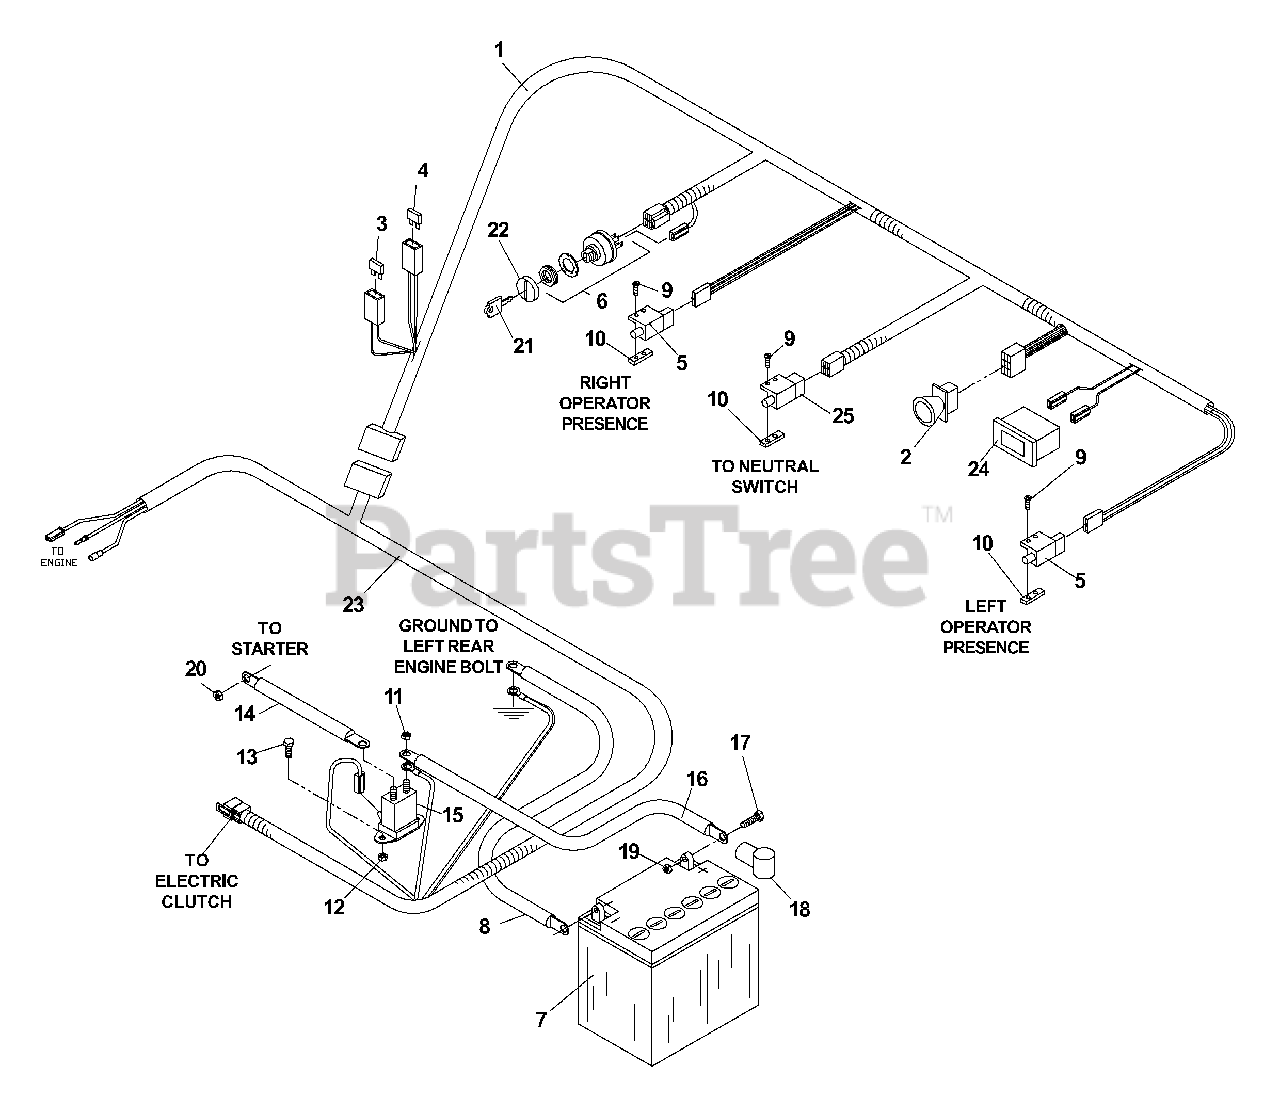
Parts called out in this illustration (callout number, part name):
1	UPPER HARNESS
2	CLUTCH SWITCH
3	FUSE 20 AMP
4	FUSE 7.5 AMP
5	SWITCH N. C.
6	IGNITION SWITCH
6	NUT, SWITCH
7	BATTERY
8	NEG. CABLE
9	SCREW #10-24
10	TAPPED PLATE
11	NUT 1/4
12	NUT 1/4 LOCK
13	HCS 1/4 X .625
14	POS. CABLE
16	POS. CABLE LONG
17	HCS 5/16 X .750
19	NUT 5/16 CTR. LOCK
20	NUT 1/4 THIN NYLOC
23	LOWER HARNESSS
24	HOUR METER
25	2 POLE SWITCH
